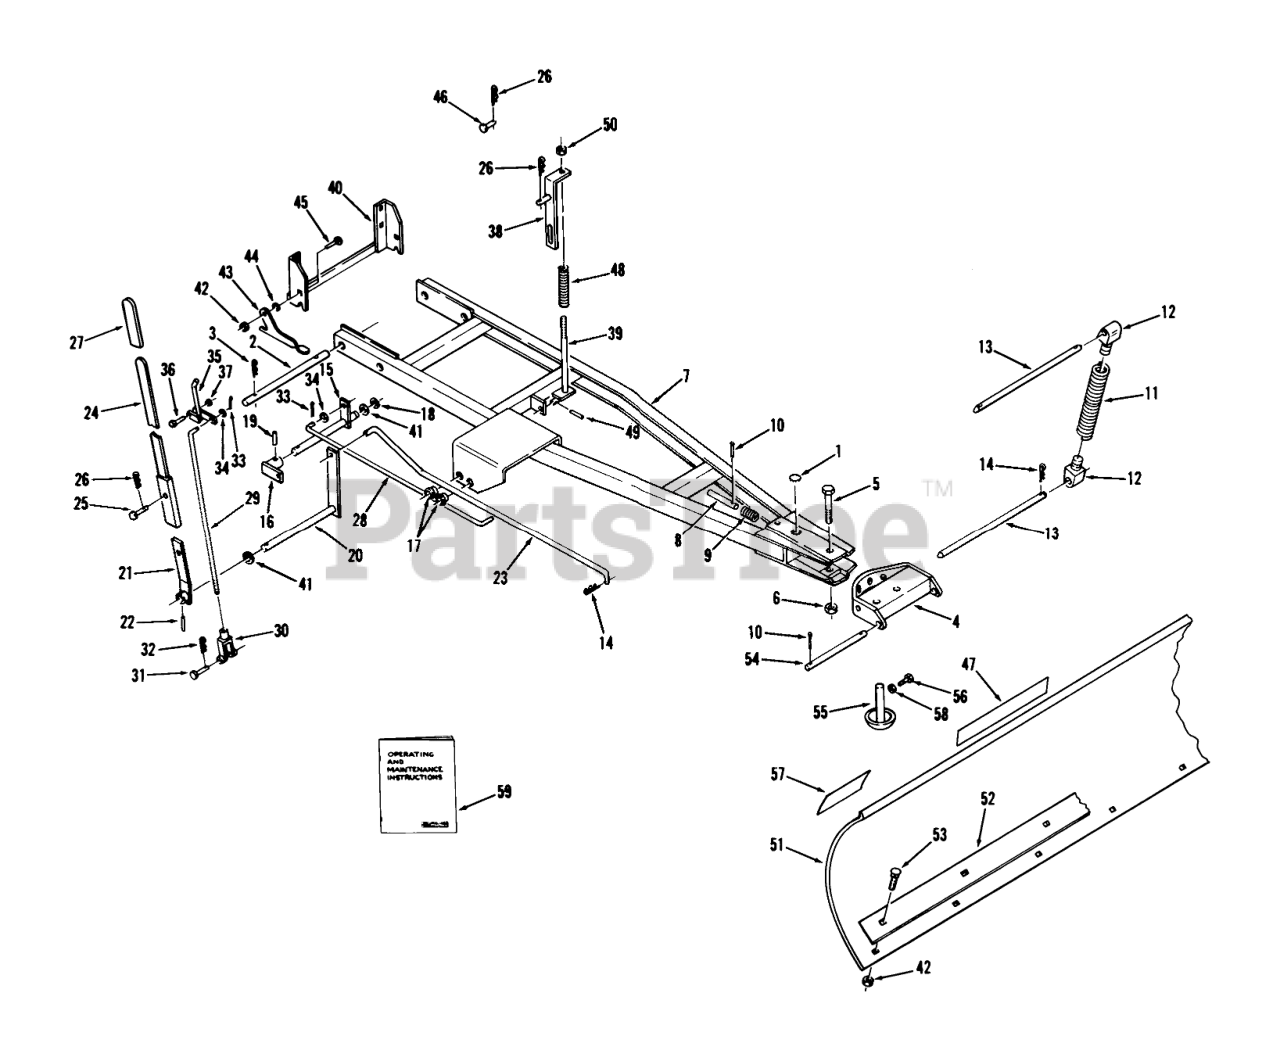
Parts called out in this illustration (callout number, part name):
1	PLUG
2	Mounting Shaft
3	Hairpin
4	Sector and Channel
5	Bolt
6	Nut
7	Frame Assembly
8	Index Pin
9	SPRING-COMPRESSION
11	Spring
12	Lug
13	ROD-TRIP RETURN
14	Hairpin
15	Bushing
16	Sat Collar
17	BUSHING
18	Snap Ring
19	SPIROL PIN 3/8X1 3/4
20	Assembly-Blade Index Arm
21	Assembly-Handle Bar
22	SPIROL PIN 3/8X1 1/2
23	Blade Control Rod
24	HANDLE ASM
25	Pin-Clevis
26	Hairpin Cotter
27	GRIP
28	ROD LOWER INDEX
29	ROD UPPER INDEX
31	Pin
33	Cotter Pin
35	Assembly Index Lever
36	Bolt
37	Nut
38	Assembly-Lift Bar
39	Assembly Lift Rod
40	Bracket
41	Shim Washer
42	NUT
43	PLATE-LATCHING
44	Washer
45	BOLT
47	DECAL-WHEEL HORSE
48	SPRING
49	Spirol Pin
50	Nut
51	Blade Assembly
52	PLATE-BLADE EDGE
53	Bolt-Carriage
54	ROD-LOWER
55	SKID SHOE ASSY R
56	Screw-Set
57	Caution Decal
58	Nut
59	Operating and Maintenance Instructions
